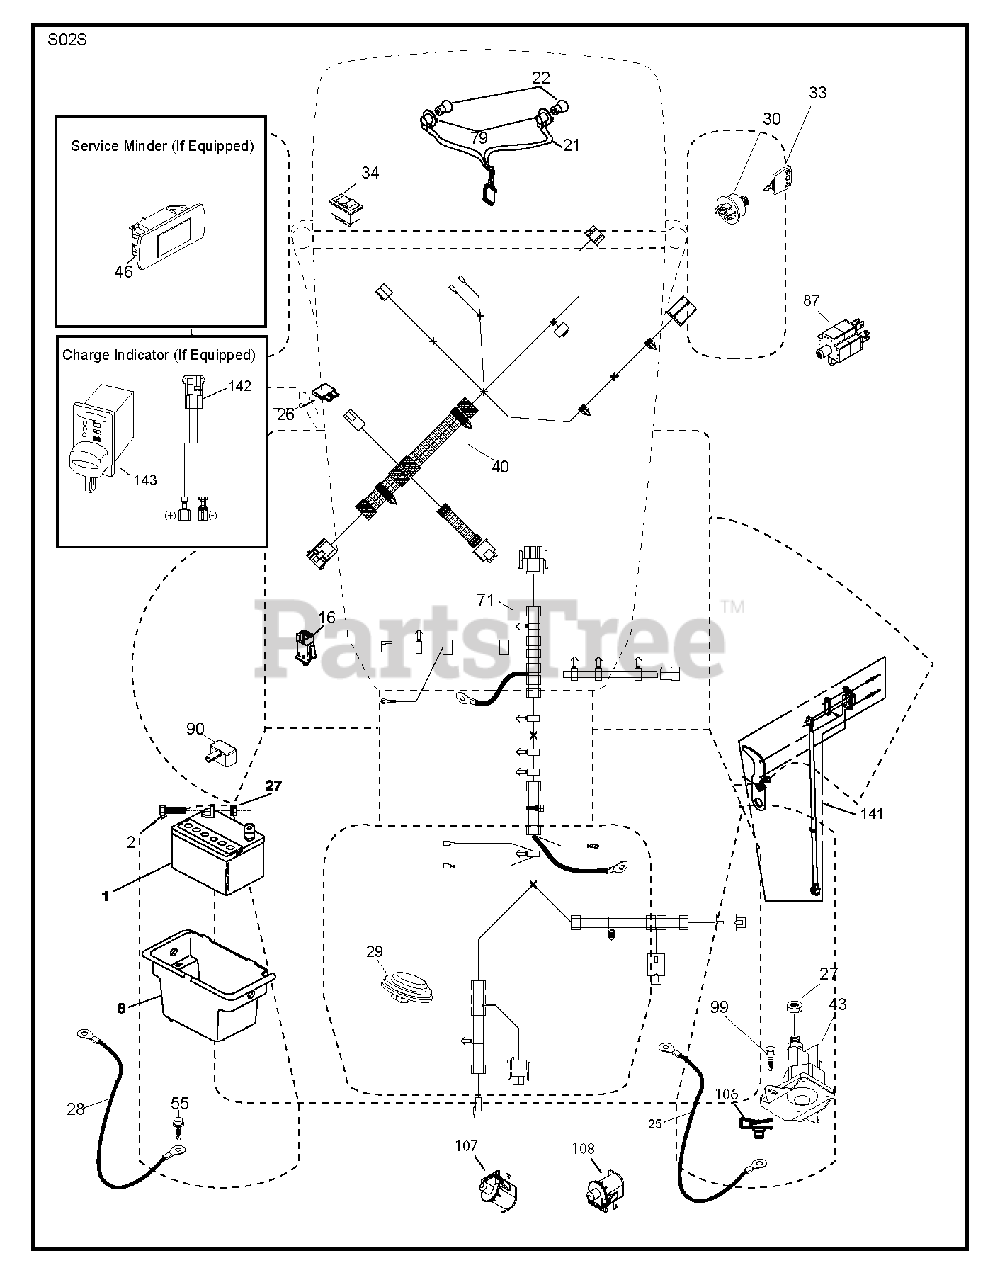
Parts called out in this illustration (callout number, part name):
1	Battery, Dry 30 Amp
2	BOLT.HEX.1/4.X.3/4.DICHROMATE
8	BOX.BATTERY.LT/SRD
16	SWITCH INTERLOOK PUSH-IN
21	HARNESS.LIGHT W/4152J BULBS
25	CABLE.BATTERY.20.RED.8 AWG
26	FUSE 20AMP
27	NUT
28	CABLE.GROUND.REAR.BATTERY.8G
29	SWITCH.SEAT.DELTA.OPC.
30	SWITCH.IGN.DELTA.W.LGH.ROS
33	KEY.CHAIN.BLISTER.PACK.GEN.INT
40	HARN.DASH.CRD.CC.SQ.RDSTRT
43	SOLENOID.STARTER.BRASS.PLUNGER
55	SCREW 5/16"
71	HARNESS.CHASS.SRD.RDY.START
79	BULB HOLDER ASM.
87	RP SWITCH.RAILMOUNT.NO-NC-NC
90	COVER.TERMINAL.BATTERY
99	SCREW HEXWSHR 1/4-20X3/4
106	1/4-20 U NUT
107	SWITCH.SNAPMOUNT.NO.#2
108	SWITCH.SNAPMOUNT.NC
141	KIT T2.ROS 71677
142	CHARGE.PORT.PIGTAIL HARNESS
143	CHARGE.PORT
